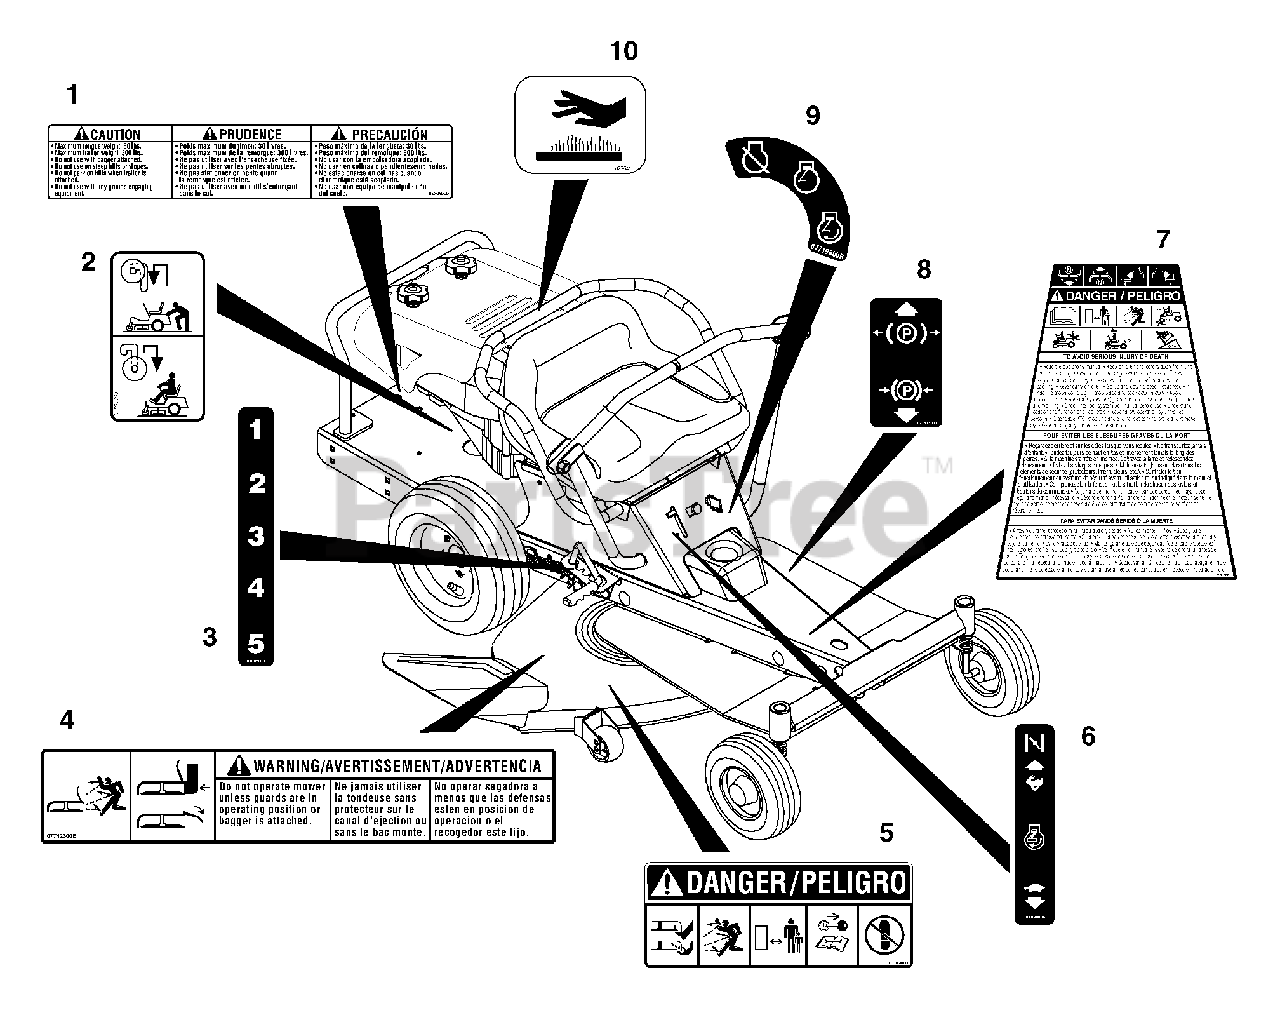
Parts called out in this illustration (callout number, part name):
1	Decal, Trailer Hitch
2	Decal, Transmission Disconnect
3	Decal, Deck Lift
4	Decal, Warning
5	Decal, Mower Pan Danger
6	Decal, Throttle
7	Decal, Sport Zoom Warning
8	Decal, Parking Brake Lever
9	Decal, Ignition
10	Decal, Hot Surface
